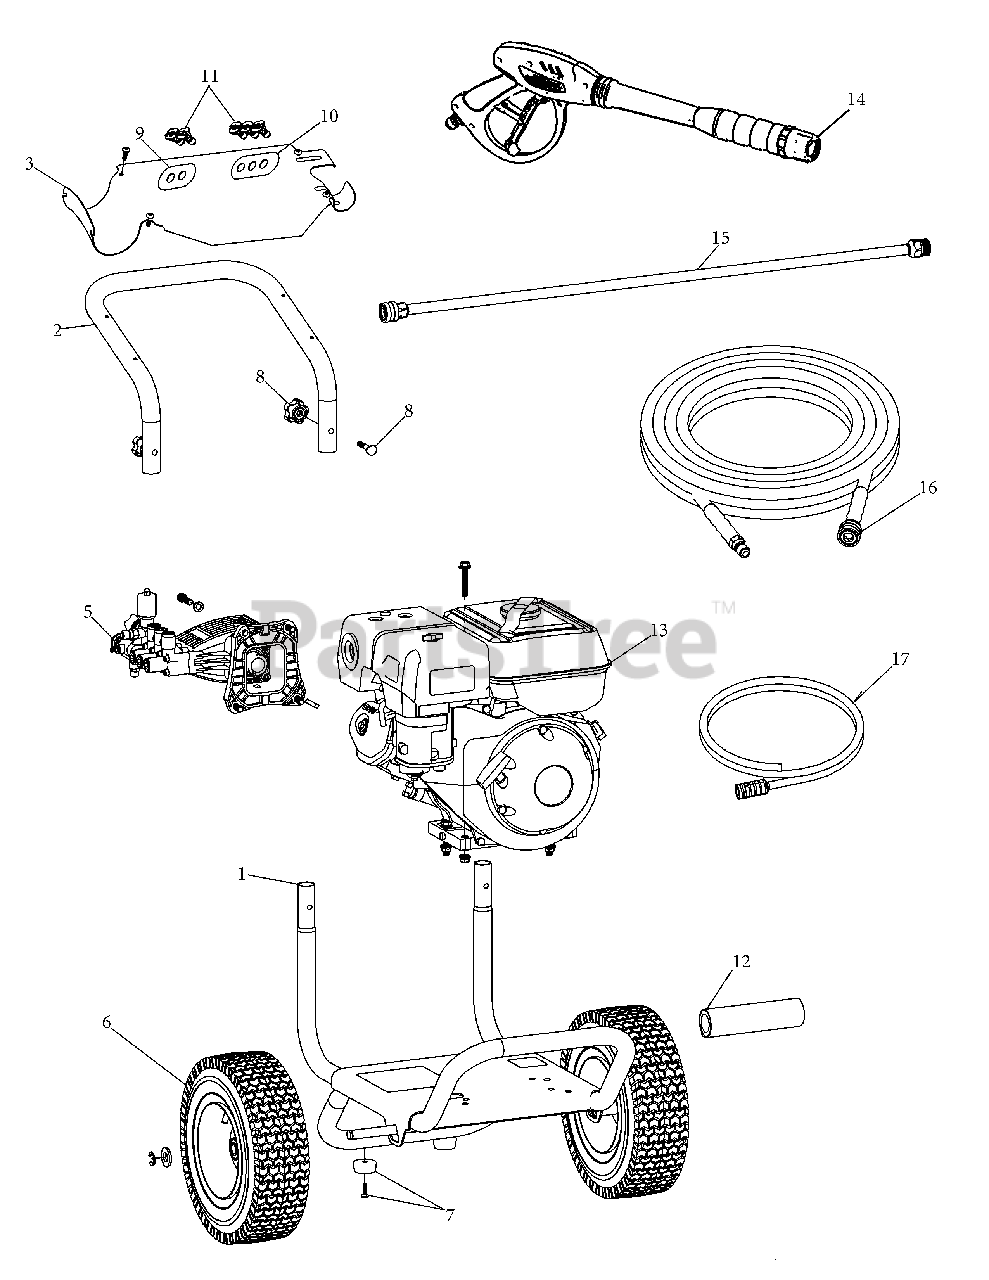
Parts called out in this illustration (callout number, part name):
1	Base Assembly, Frame
2	Handle, Upper
3	Panel, Dashboard w/Label
5	Pump Assembly
6	Wheel Assembly
8	Knob, Handle Mounting
9	Nozzle Holder, 2pc
10	Nozzle Holder, 3pc
11	Nozzle Set 5pc
12	Grip, Handle
13	Engine Assembly
14	Gun, Spray
15	Wand, Spray Gun 16"
16	Hose, Spray 26'
17	Hose, Soap w/Filter
